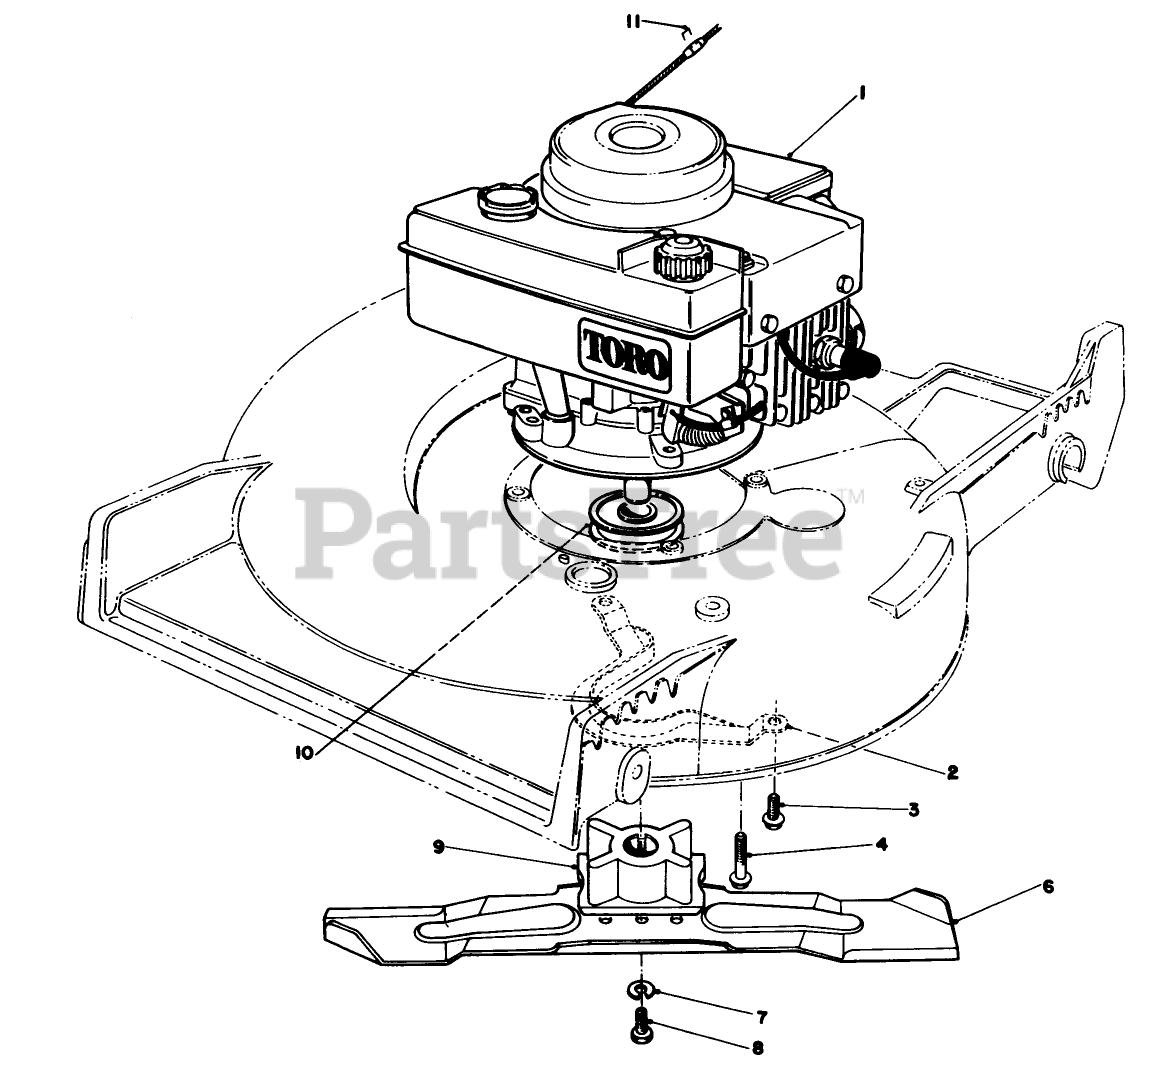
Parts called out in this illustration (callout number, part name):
2	BELT GUIDE
3	SCREW-HWHTF
4	3/8-16 X 2 CAPSCREW
6	BLADE-21in
7	WASHER-LOCK
8	SCREW-BLADE
9	BLADE RETAINER
10	PULLEY-DRIVE, ZONE START
11	Staple
